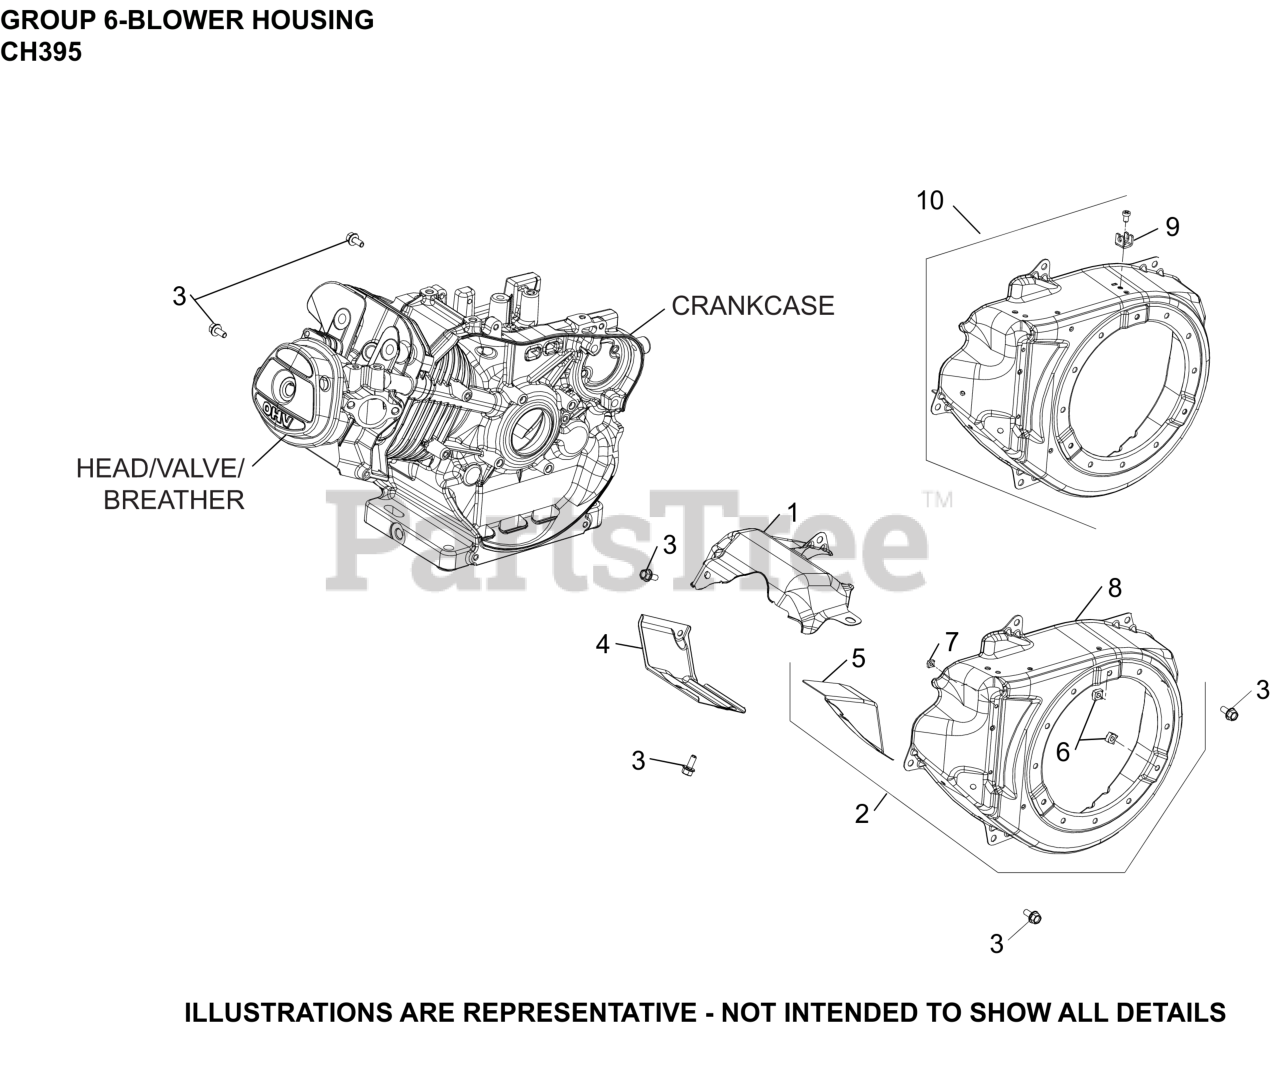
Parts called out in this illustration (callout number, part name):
1	SHIELD, UPPER HEAT
2	HOUSING, BLOWER ASSEMBLY-USE 17 027 53-S
4	SHIELD, CYLINDER HEAD
5	SHIELD, OUTSIDE CYLINDER HEAD
9	SCREW, M6 X 8 HEX FLANGE HEAD
